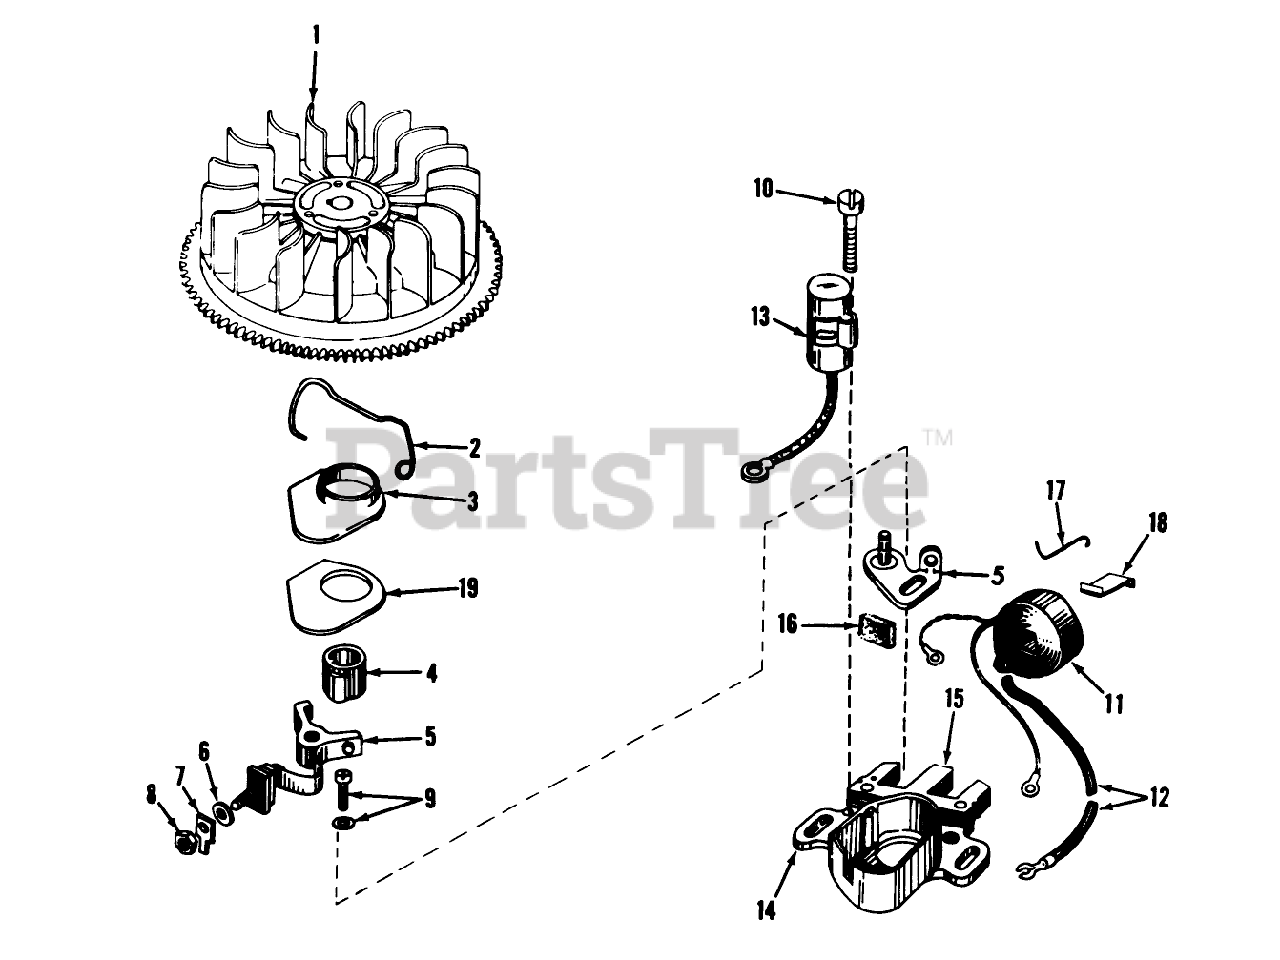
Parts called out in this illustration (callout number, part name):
1	Flywheel
2	Spring Breaker Box
3	Cover, Dust
4	Cam-Breaker
5	Breaker Assy.
6	Washer
7	Terminal
8	DECAL
9	Breaker Screw
10	Condenser Screw
11	Coil Assy. (Incl. No. 12)
12	Wire, Lead
13	Condenser
14	Core Plate
15	Stator Assy., (Incl. Nos. 2, 3, 5 thru 14 16 thru 19)
16	Felt,Cam Wiper
17	Clip, Coil
18	Spring Coil Wedge
19	Gasket, Dust Cover
